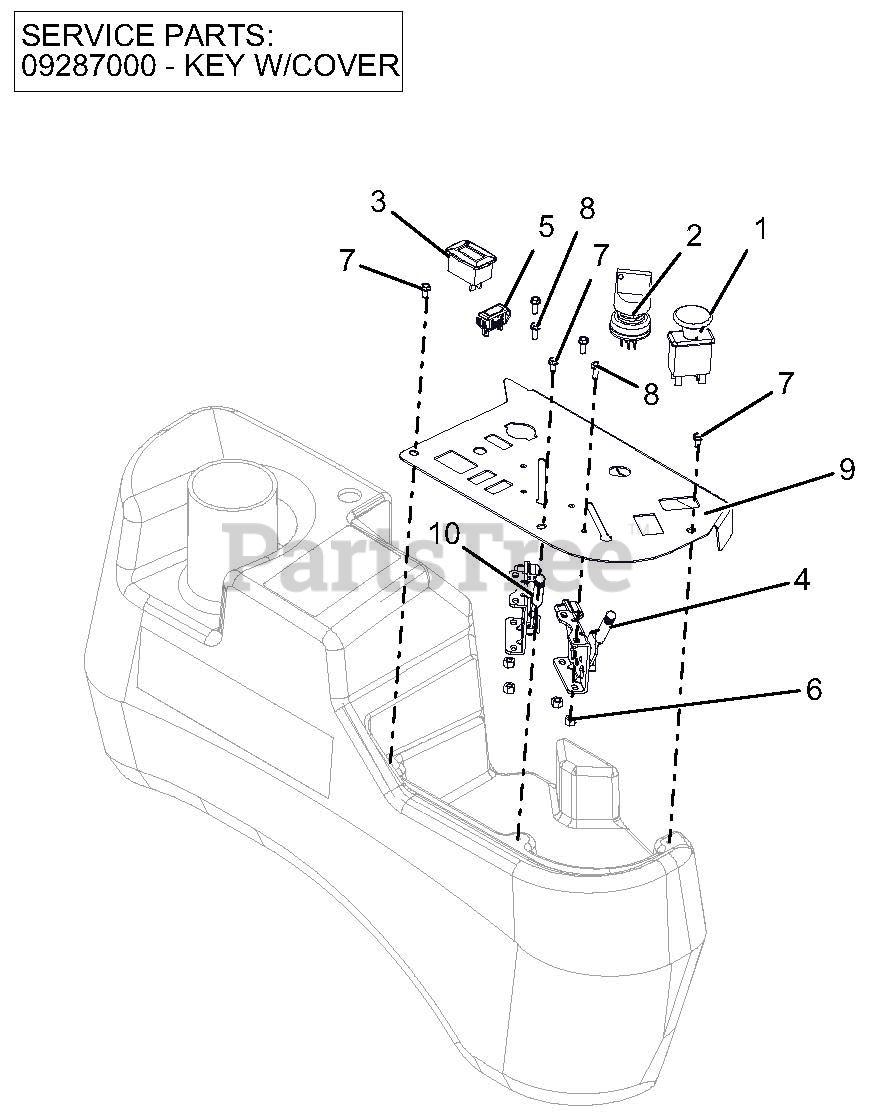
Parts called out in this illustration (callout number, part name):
1	SWITCH, CLUTCH
2	SWITCH, IGNITION
3	METER, HOUR W/MAINTENANCE
4	CABLE, PRO-CONTROL THROTTLE
5	LIGHT, INDICATOR
6	NUT-LK-NYL #10-24 YWZC
7	SCR-MCH 10-24X.38 HWHSTAINLESS
8	@SCR-MCH 10-24X.50 HWH YWZC
9	PANEL, CONTROL
10	CABLE, PRO-CONTROL THROTTLE
11	KEY W/ COVER
